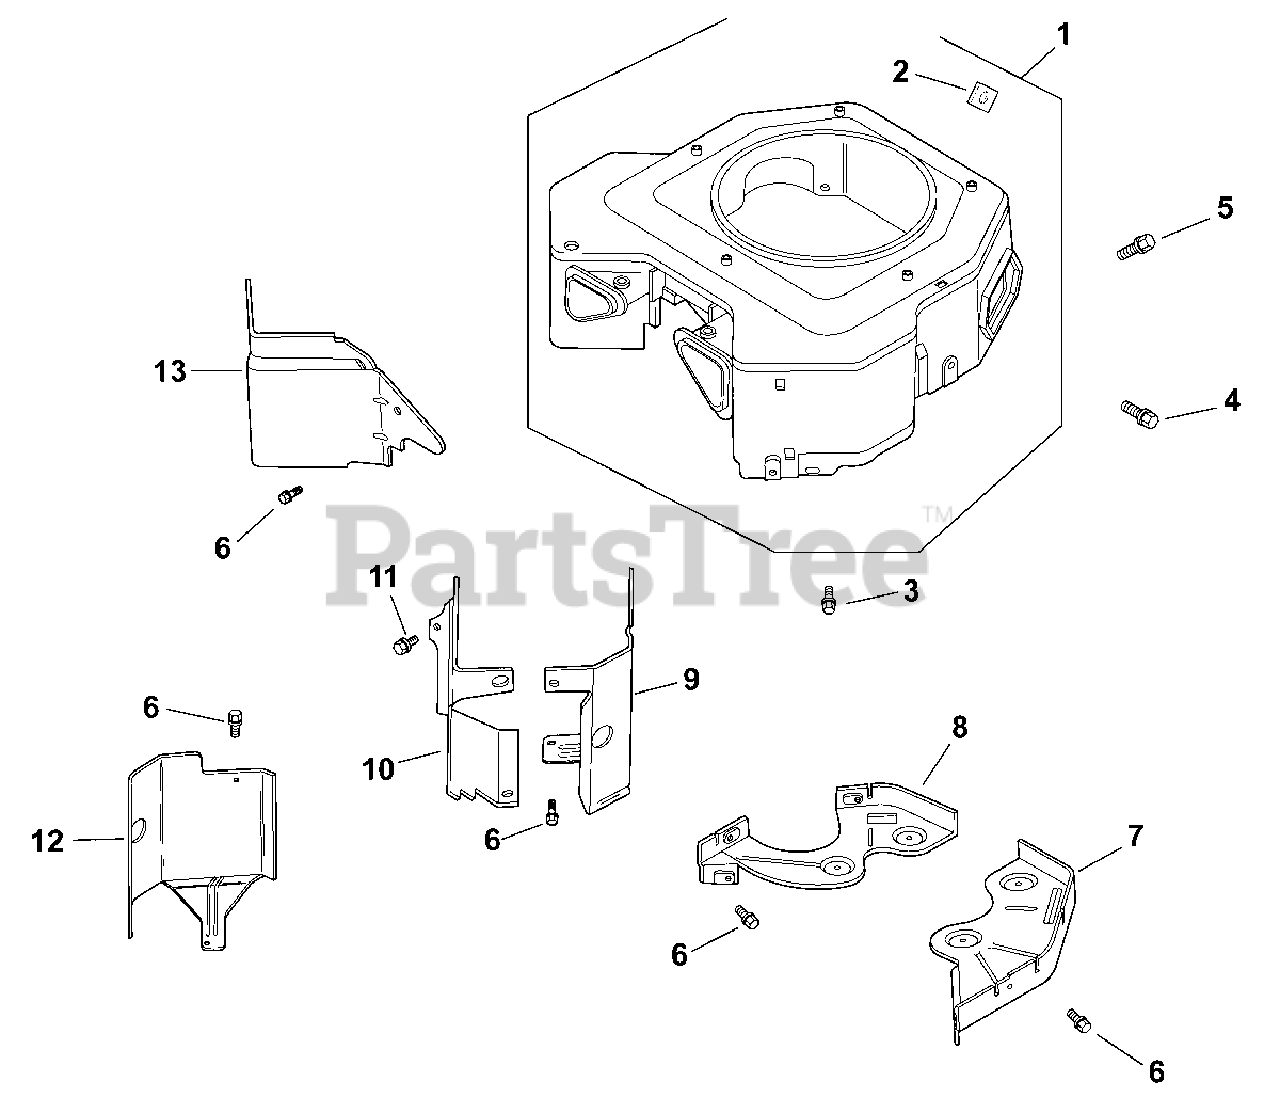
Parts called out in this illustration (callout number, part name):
1	KIT, BLOWER HOUSING USE 24 027 451-S
2	NUT, PLASTIC (KM)-USE 25 100 37-S
3	SCREW, FLG THD FRM M5X.8X20-(#25086399S)
4	SCREW,FLG THD FRM M5X0.8X16-(#25086398S)
5	SCREW, HVY FLG M5X.8X16
6	SCREW,FLG THD FRM M6X1.0X16-(#25086397S)
7	PLATE, BACKING - #2 SIDE-USE 24 146 59-S
8	PLATE, BACKING - DISCONTINUED
9	BAFFLE,VALLEY #2SIDE(KM)-USE 24 063 88-S
10	BAFFLE, VALLEY (CV)-USE 24 063 93-S
11	SCREW, FLG THD FRM M5X.8X10
12	BAFFLE, RIGHT BARREL-USE 24 063 85-S
13	BAFFLE, VALLEY #2 SIDE-USE 24 063 94-S
